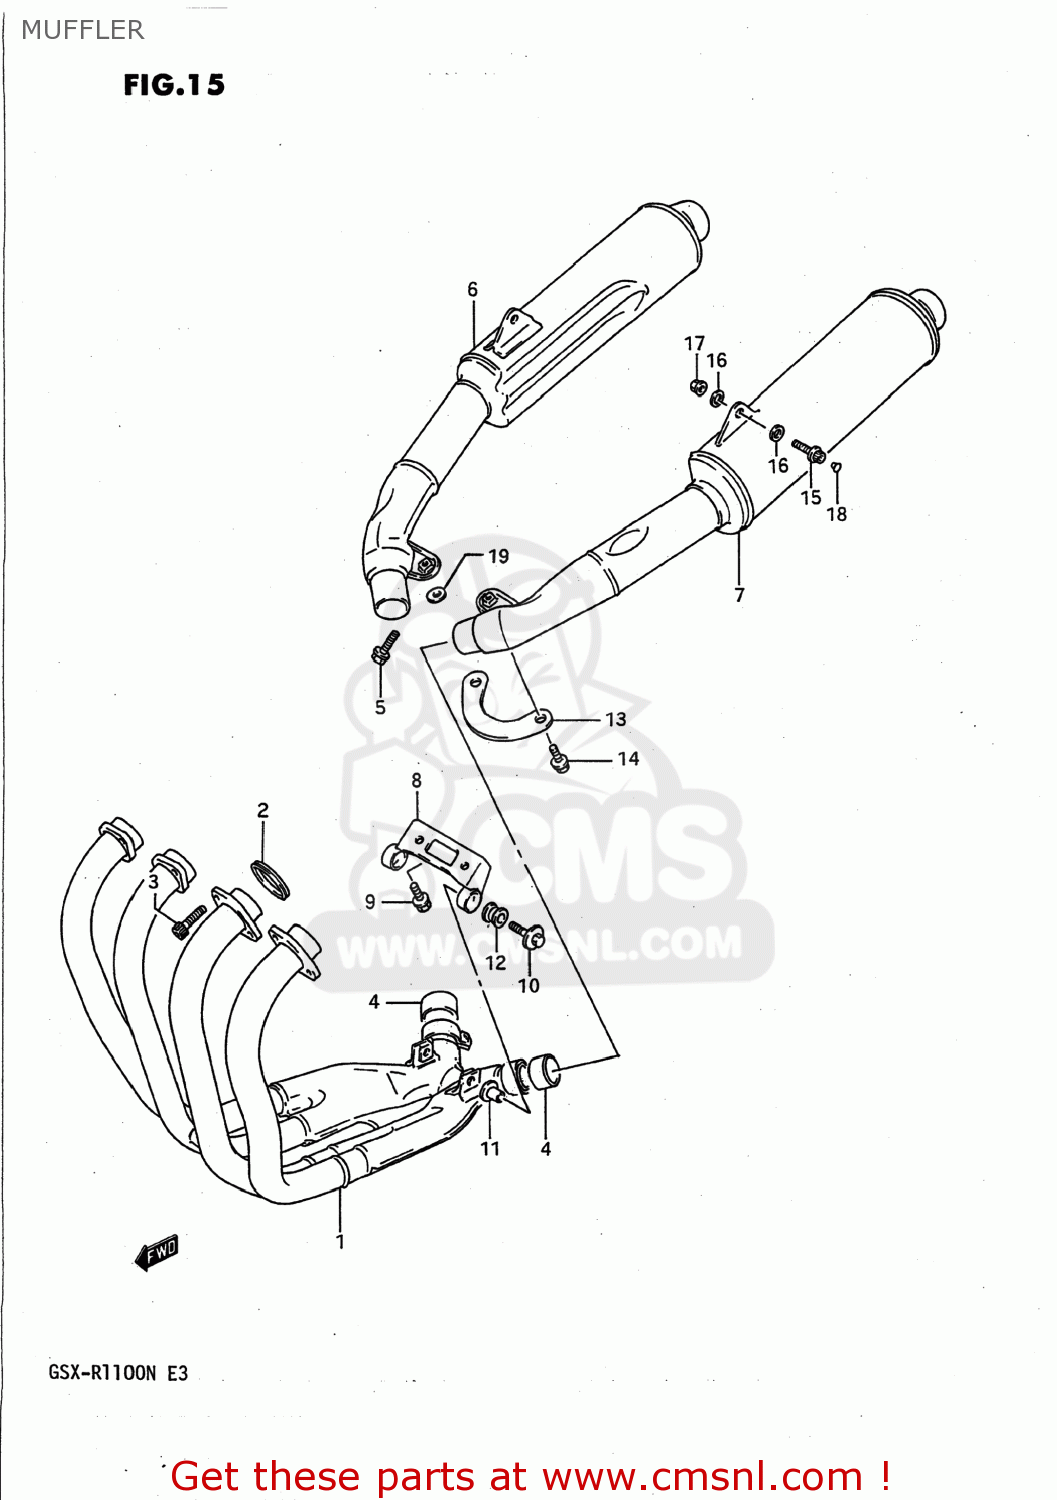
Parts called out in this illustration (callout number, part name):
1	EXHAUST ASSEMBLY
2	GASKET,EXHAUST PIPE (NAS)
3	BOLT
4	CONNECTOR,MUFFLER
5	BOLT 8X40
6	BODY,MUFFLER,RIGHT
7	BODY,MUFFLER,LEFT
8	DAMPER,MUFFLER SUPPORT CTR
9	BOLT(8X20)
10	BOLT(8X35)
11	SPACER(8.6X12X18.5)
12	CUSHION
13	PLATE,MUFFLER JOINT
14	BOLT
15	BOLT
16	WASHER (10.5X24X2.3)
17	NUT
18	CAP(OD:12)
19	WASHER (8.5X29X1.6)
